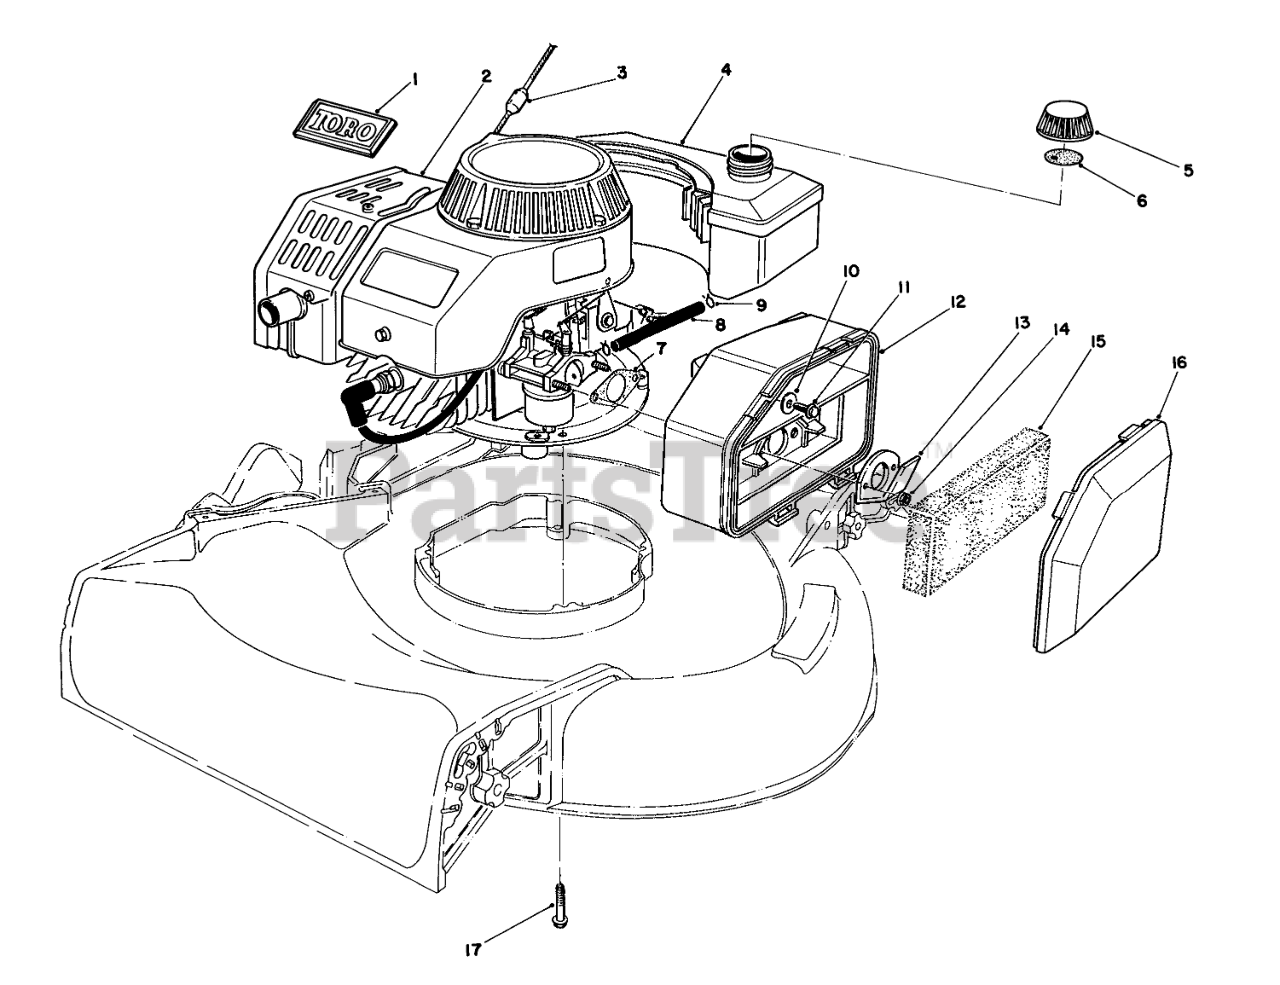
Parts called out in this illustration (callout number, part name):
1	TORO LOGO PLT
2	Engine
3	STOP-ROPE
4	Fuel Tank Assembly
5	Gas Cap Assy. (Incl. Ref. #6)
6	GAS CAP GASKET
7	GASKET-AIR CLEANER
8	FUEL LINE
9	CLAMP-HOSE
10	WASHER-FLAT
11	SCREW-HH
12	AIR CLEANER
13	SPIT BACK DEFLECTOR
14	NUT-LOCK
15	FILTER
16	AIR CLEANER COVER
17	FLG SCREW,3/8-16X2.000
